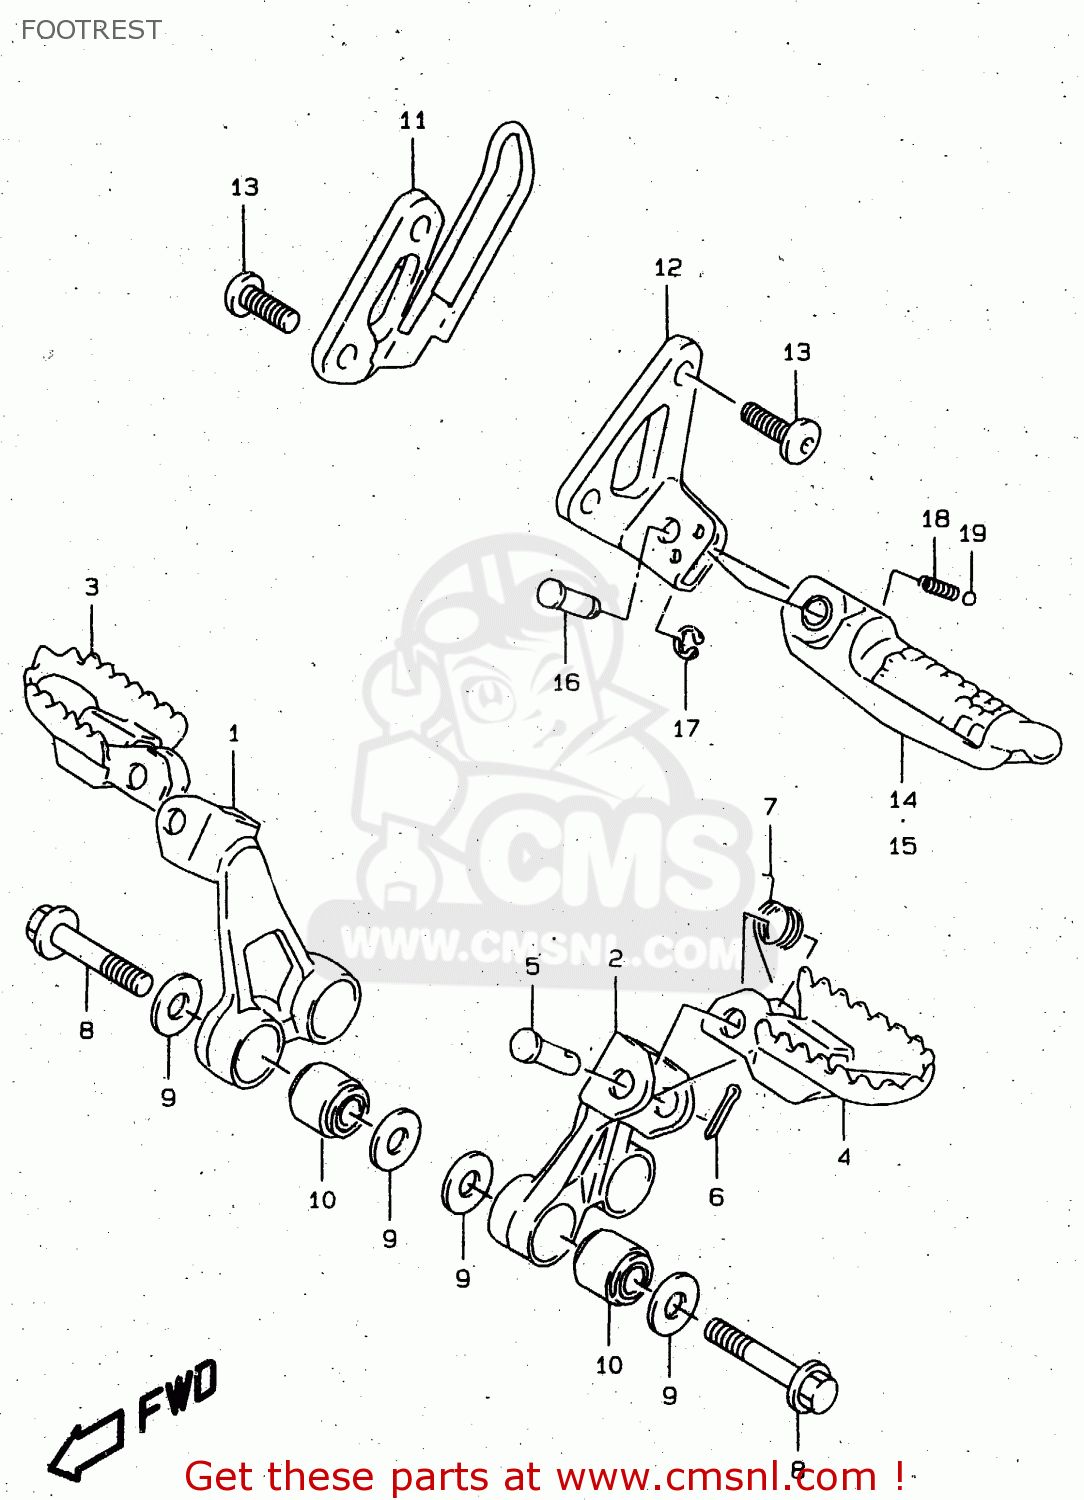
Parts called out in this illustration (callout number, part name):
1	BRACKET,FR FOOTREST,R
2	BRACKET,FR FOOTREST,L
3	FOOTREST,FRONT,RIGHT
4	FOOTREST,FRONT,LEFT
5	PIN
6	PIN 20X20
7	SPRING
8	BOLT(10X50)
9	WASHER
10	BUSH(10.2X25X19)
11	BRACKET,PILLION FOOT,R(BLACK)
12	BRACKET,PILLION FOOT,L(BLACK)
13	BOLT 8X20
14	BAR,PILLION FOOTREST,R
15	BAR,PILLION FOOTREST,L
16	PIN
17	E.RING
18	SPRING
19	BALL
